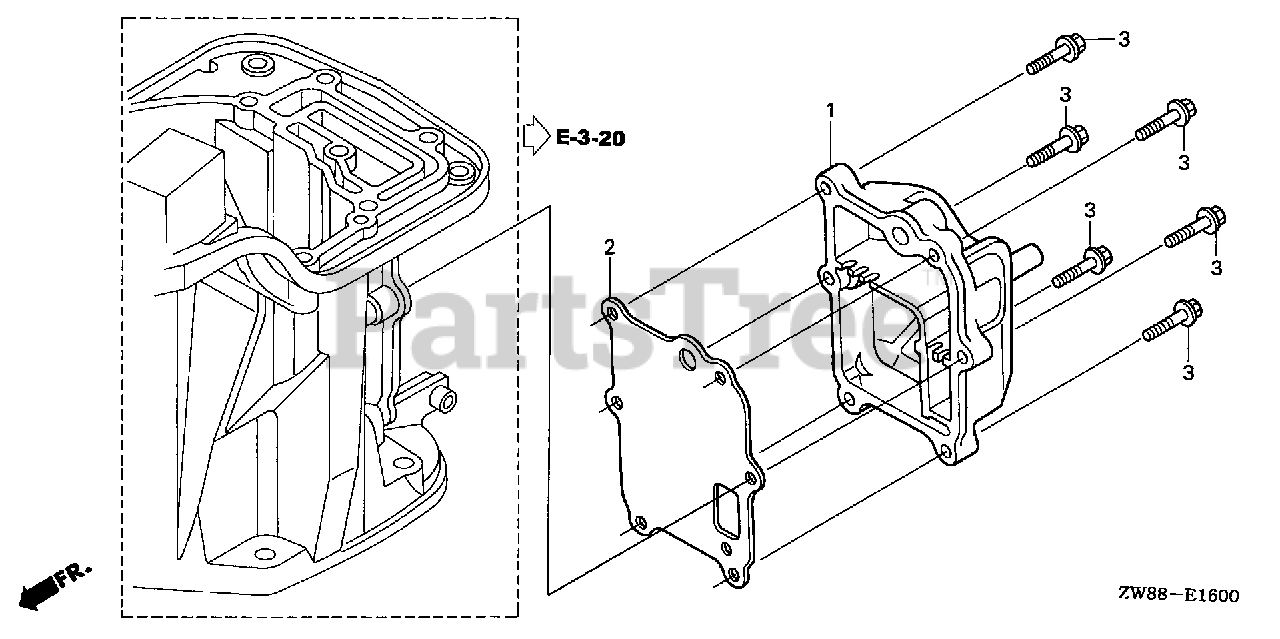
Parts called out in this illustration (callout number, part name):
1	COVER, EX. CHAMBER
2	GASKET, EX. CHAMBER
3	BOLT, FLANGE (6X23)
